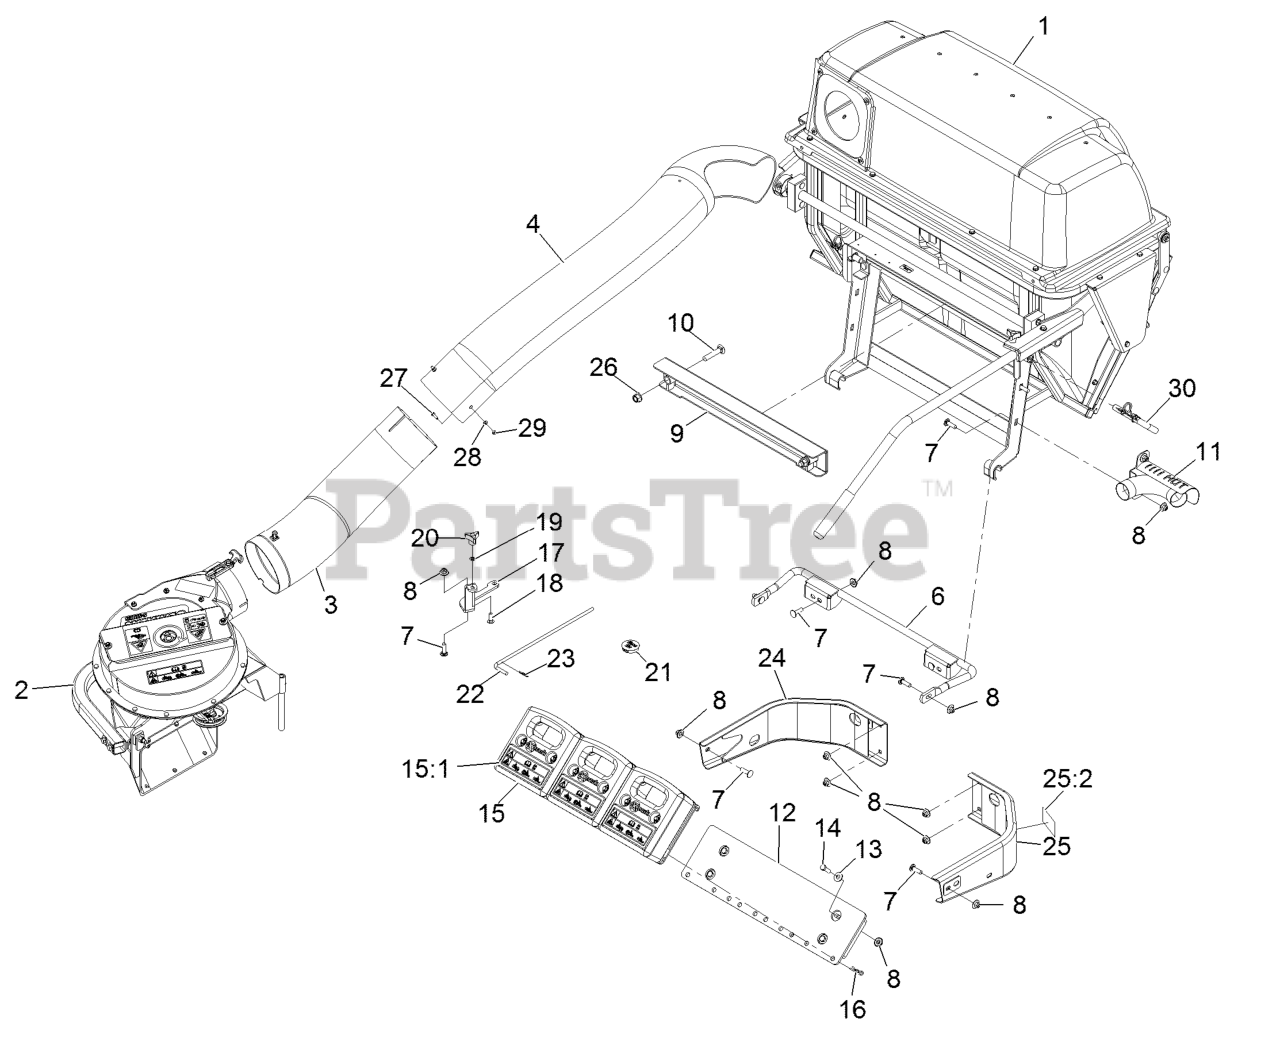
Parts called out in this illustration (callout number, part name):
1	ASM,Hopper Sm Qds
2	ASM, Blower Small - Svc Only
3	Lower Tube ASM
4	Tube-Upper
6	Mount-Bagger, Lower
7	Bolt-Carriage 3/8-16 X 1 1/4
8	Nut-Nyloc 3/8-16 Flg
9	Mount-Bagger, Upper
10	Bolt-Carriage 1/2-13 X 2 1/2
11	Exhaust Diverter ASM
12	Wld, Mount Toeboard Weight
13	Washer-3/8 Std
14	Screw-HH 3/8-16 X 1 1/4
15	Asm, Weight (103-6364-01) W/Decals
15:1	Decal-Warning Weight
16	Hairpin-Cotter
17	Bracket, Small Uv Belt Cover
18	Bolt-Carriage 5/16-18 X 1
19	Ring-Bolt Retaining
20	Knob-3 Prong
22	Pin, Chute Pivot
23	Hairpin-Cotter
24	Bumper-RH
25	LH Bumper ASM
25:2	Decal-Warning
26	Nut-Lock 1/2-13
27	Screw-HWH #10-24 X 3/4
28	Washer-#10 Std
29	Nut-Nyloc #10-24
30	Pin-Mount, Bagger
